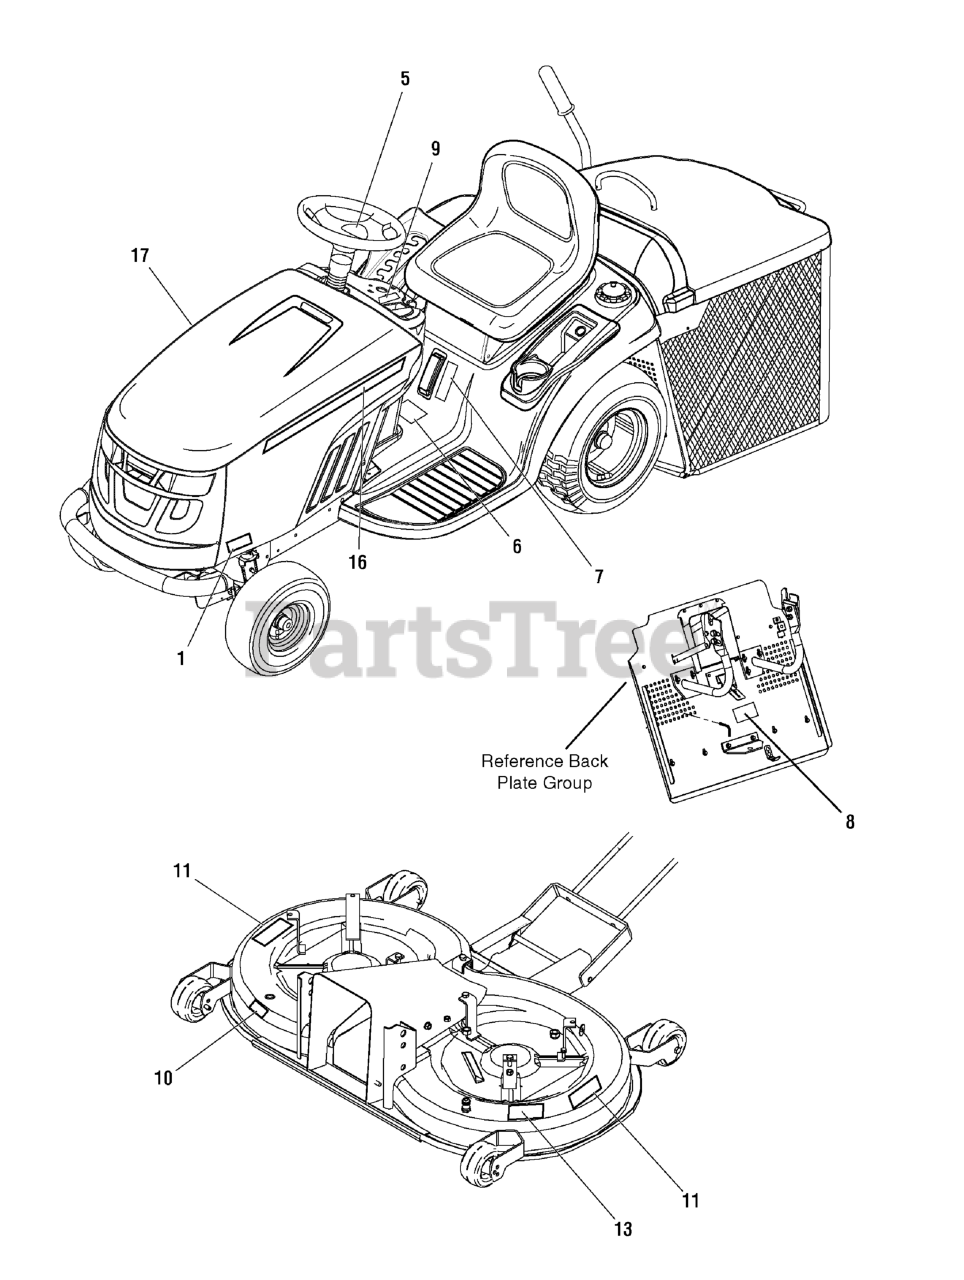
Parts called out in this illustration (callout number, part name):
1	DECAL, LT180RD
5	DECAL, Steering Wheel
6	DECAL, Tunnel Cover Warnings, Export
7	DECAL, Fuel Level
8	DECAL, Hydro Release
9	DECAL, Ignition Switch Symbols
10	DECAL, Noise
11	DECAL, Safety
13	DECAL, Murray 102cm
16	DECAL, Murray, L.H.
17	DECAL, Murray, R.H.
